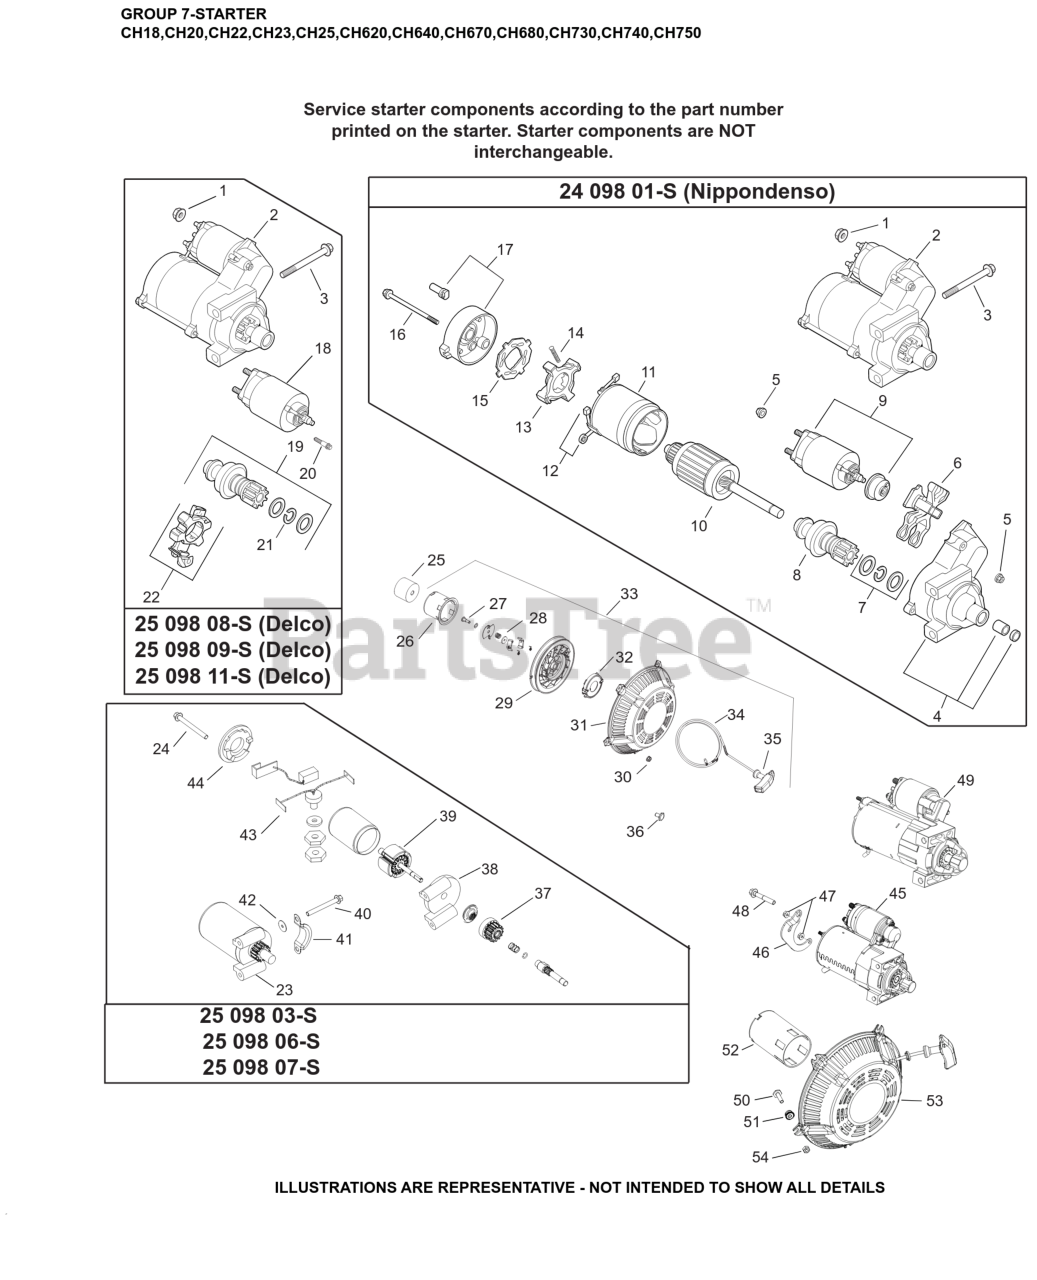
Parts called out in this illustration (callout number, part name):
1	NUT, FLG M8X1.25
2	STARTER, SOLENOID SHIFT-(#2509824S)
3	SCREW, FLG M8X1.25X80
